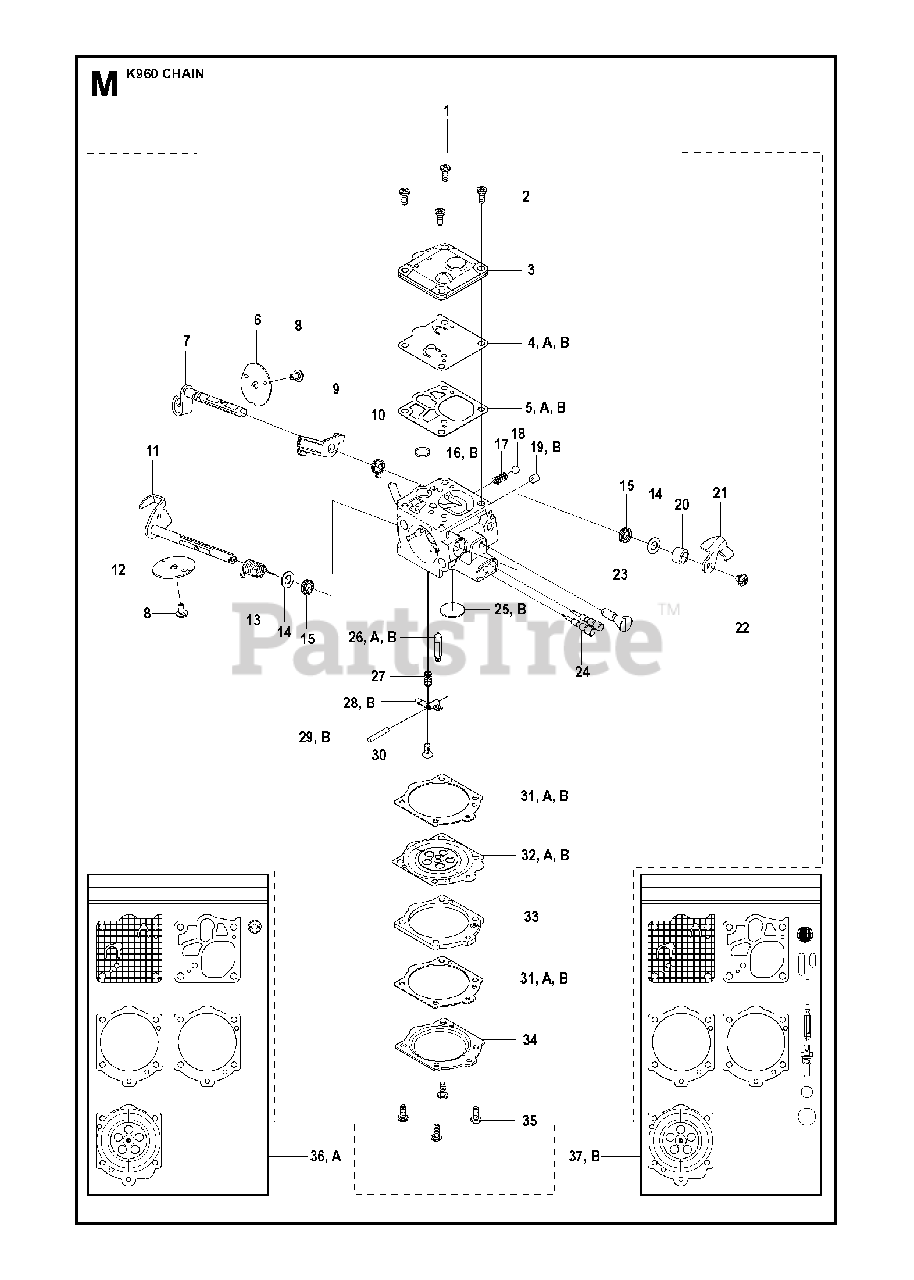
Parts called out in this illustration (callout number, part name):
1	CARBURETTORIncl. 2 - 32, Walbro RWJ-3
3	PUMP COVER
4	DIAPHRAGM PUMPA, B
26	VALVE -INLET NEEDLEA, B
29	PIN-METERING LEVERB
32	DIAPHRAGM ASSYA, B
36	GASKET KITKit A. D10-RWJ
37	REPAIR KITKit B. K10-RWJ
